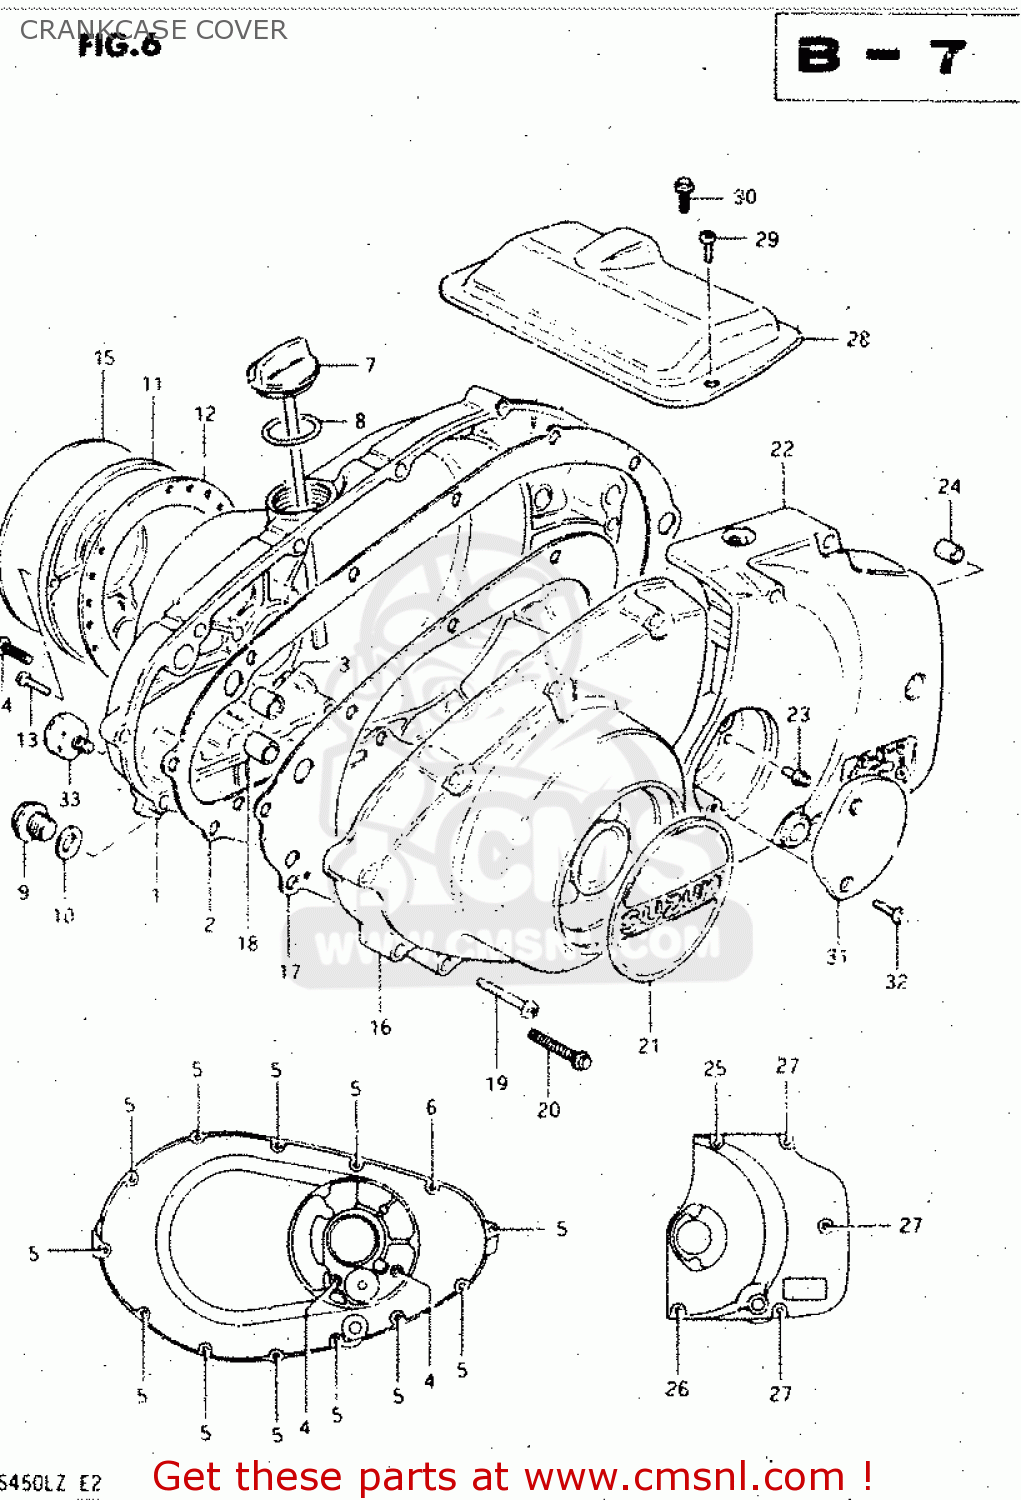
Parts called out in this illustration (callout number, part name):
1	COVER,CLUTCH
2	GASKET,CLUTCH COVER (MCA)
3	PIN
4	SCREW
5	BOLT (6X35)
6	BOLT
7	GAUGE,OIL LEVEL
8	O-RING
9	PLUG (14X12)
10	GASKET(14X19.2X2) (NAS)
11	COVER,CONTACT BREAKER
12	GASKET,CONTACT BREAKER COVER (NAS)
13	SCREW
14	BOLT 5X16
15	EMBLEM,MAGNETO COVER
16	COVER
17	GASKET,MAGNETO COVER (MCA)
18	PIN
19	SCREW (6X35)
20	BOLT (6X35)
21	EMBLEM,MAGNETO COVER
22	COVER,SPROCKET
23	NIPPLE
24	PIN
25	SCREW 6X65
26	SCREW
27	SCREW
28	COVER,STARTER MOTOR
29	SCREW
30	BOLT
31	CAP,CLUTCH RELEASE ADJUST
32	SCREW 5X12
33	SWITCH ASSEMBLY
